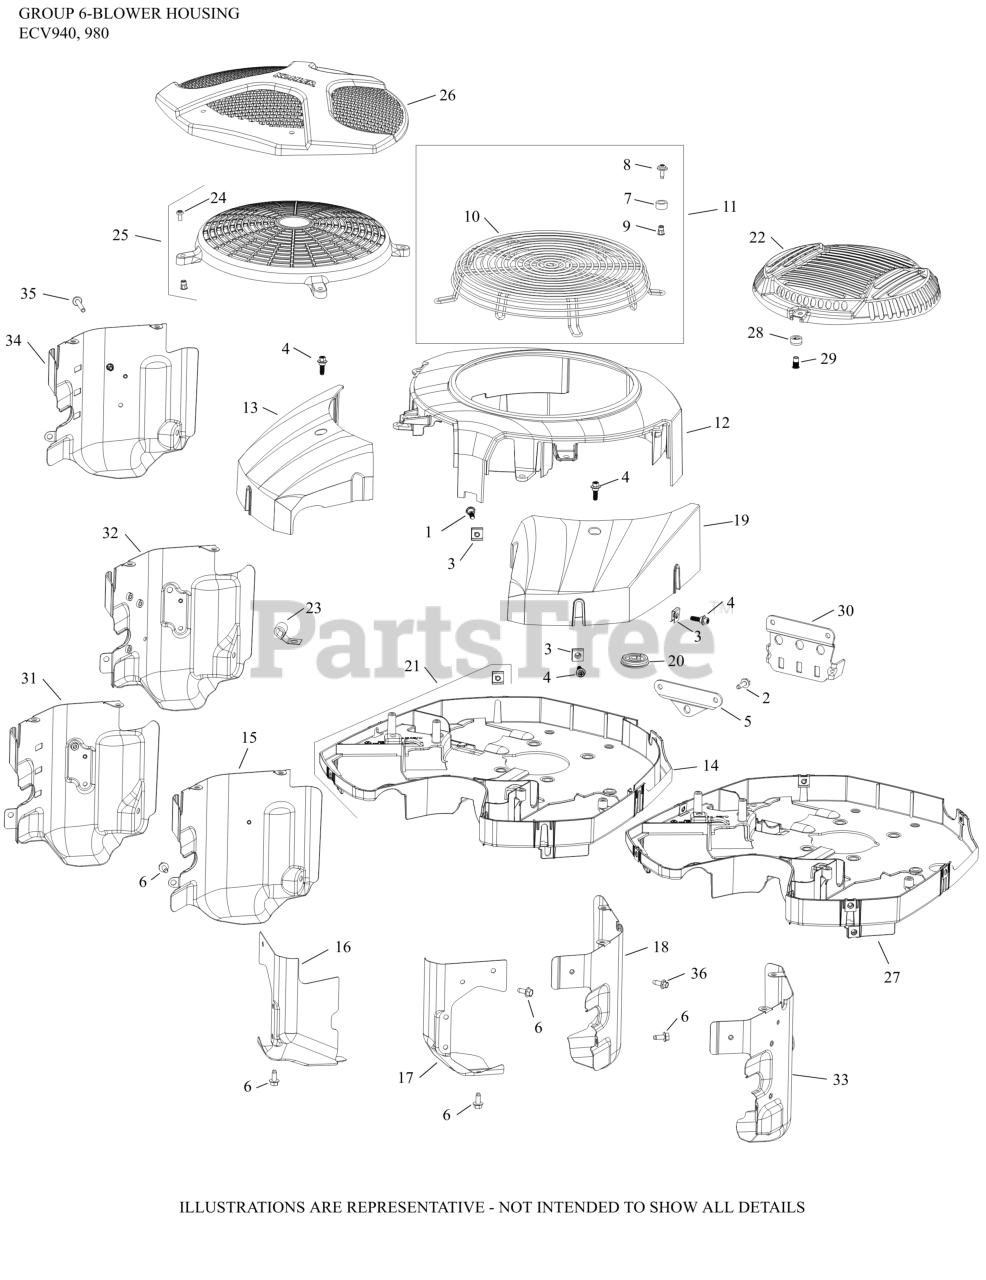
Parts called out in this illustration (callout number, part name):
1	SCREW, SHD THD FRM M6X1X26
2	SCREW, THREAD FORMING
3	CLIP, BAFFLE MOUNTING
4	SCREW, SHD THD FRM
6	SCREW, THREAD FORMING
8	SCREW, SEMS
9	INSERT, THREADED-(#2533219S)
12	KIT, BLOWER HOUSING
13	SHROUD, #1 CYLINDER
14	SHROUD, BACKING-USE 62 424 19-S
15	BAFFLE, BARREL (#1 CYL)-USE 62 063 48-S
16	BAFFLE, VALLEY #1 CYLINDER
17	BAFFLE, VALLEY #2 CYLINDER
18	BAFFLE, BARREL (#2 CYL)
19	SHROUD, #2 CYLINDER
20	CGROMMET, WIRING HARNESS
21	SHROUD AND CLIP ASSEMBLY
22	GUARD, GRASS SCREEN (METAL)
30	STRAP, LIFTING/ FUSE HOLDER
